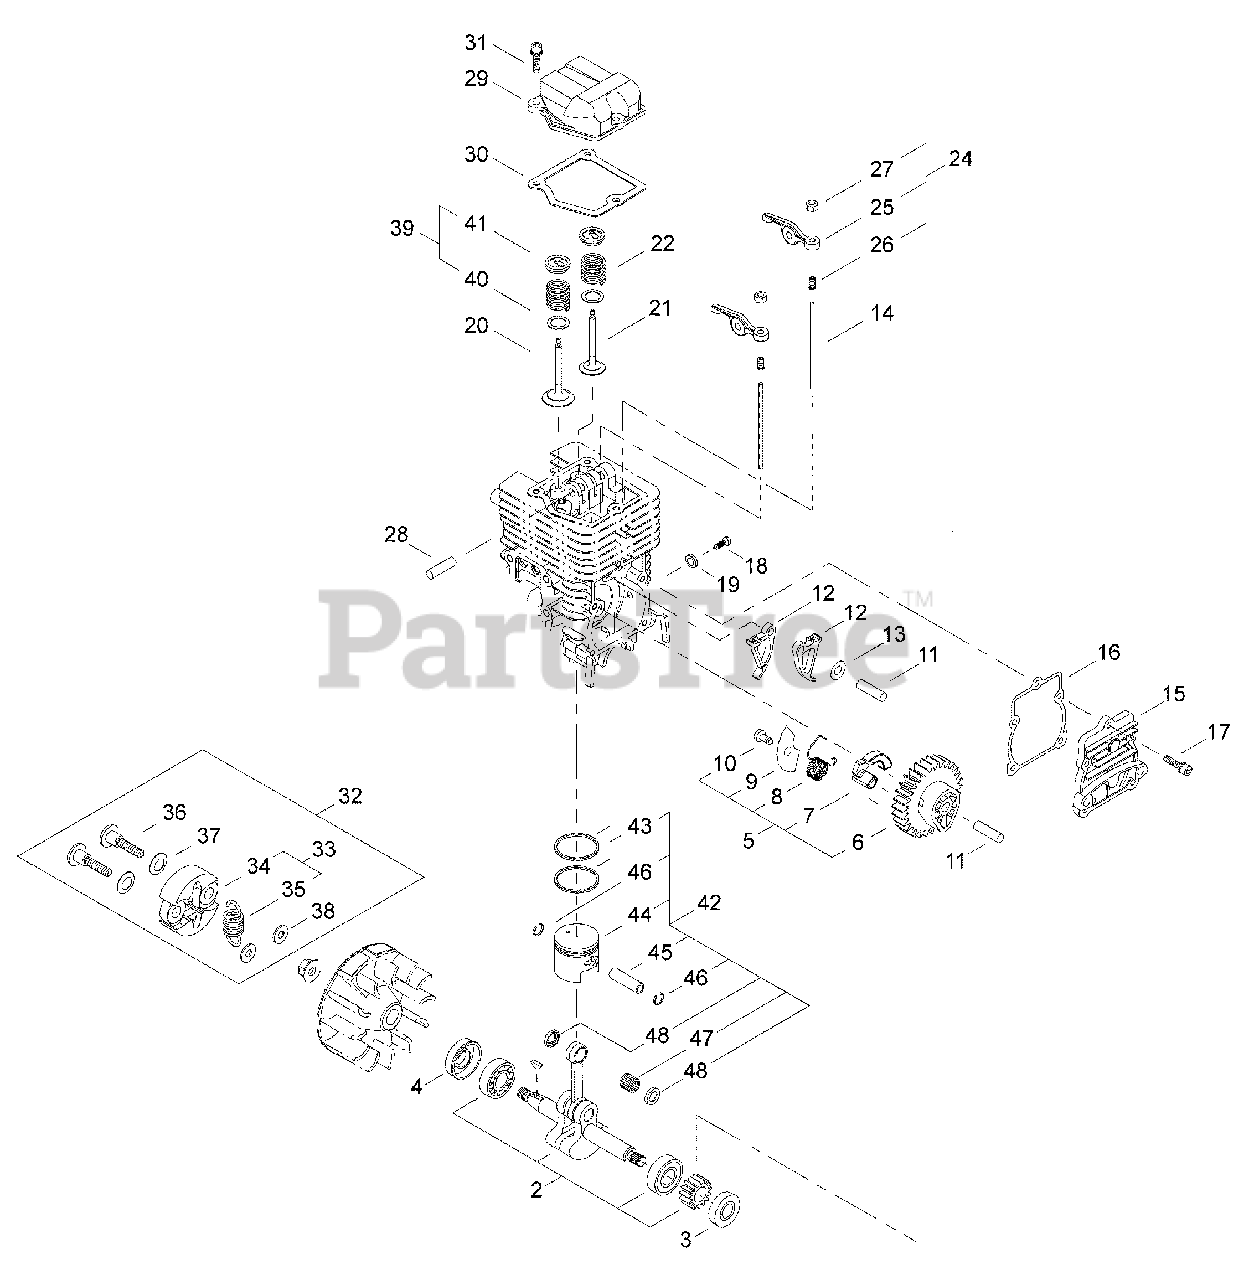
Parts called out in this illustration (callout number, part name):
2	CRANKSHAFT ASSY
3	SEAL, OIL 12
4	SEAL, OIL 12
5	CAM GEAR ASSY
6	GEAR, CAM
7	WEIGHT
8	SPRING
9	PLATE, COVER
10	SCREW, TAPPING 4×6
11	PIN, LOCATING Ø5×29.8 MM
12	FOLLOWER, CAM
13	WASHER 5 MM
14	PUSHROD
15	COVER, CAM GEAR
16	GASKET, CAM GEAR
17	BOLT M4×14
18	SCREW M5
19	WASHER Ø10ר5.5×2
20	VALVE, INTAKE
21	VALVE, EXHAUST
22	SPRING, VALVE
24	ARM ASSY, ROCKER
25	ARM, ROCKER
26	SCREW, ADJUSTER
27	NUT, ADJUSTER LOCK 5
28	SHAFT, ROCKER ARM Ø5×31.8 MM
29	COVER, ROCKER ARM
30	GASKET, ROCKER ARM
31	BOLT M4×12
32	CLUTCH ASSY
33	SHOE ASSY, CLUTCH
34	SHOE, CLUTCH
35	SPRING, CLUTCH
36	BOLT, CLUTCH
37	WASHER, SPRING
38	WASHER 6 MM
39	RETAINER SET, VALVE
40	WASHER, VALVE 9
41	RETAINER, VALVE
42	PISTON KIT
43	RING, PISTON
44	PISTON
45	PIN, PISTON
46	RING, SNAP
47	BEARING, NEEDLE 9
48	WASHER, THRUST 9
